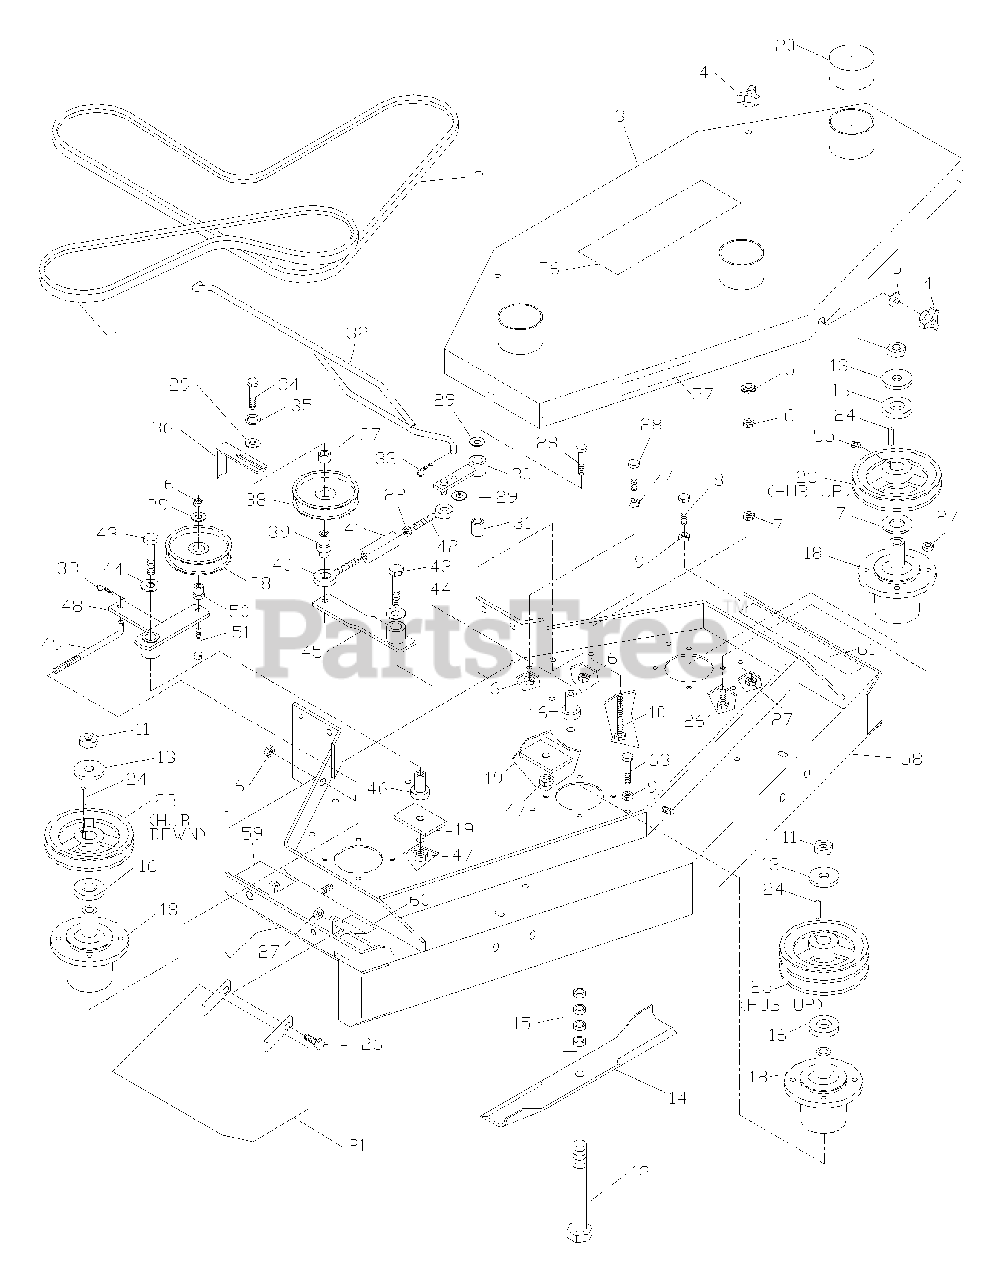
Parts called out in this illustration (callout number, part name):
1	AUX. BLADE BELT
2	BLADE BELT 48
3	48" BELT SHIELD
4	THREE PRONG KNOB
5	3/8 SEALING WASHER
8	HCS 5/16CX3
9	HFLN 5/16C
10	TAPBOLT-3/8C X 4 1/2
12	HCS 5/8F X 8 1/2
12	HCS 5/8F X 9(CENTER)
13	SUPPORT WASHER
14	BLADE 16 1/4"
15	BLADE SPACERS
17	MACH. BUSHING
18	HOUSINGASM.
21	DEFLECTOR CHUTE
22	5/16C HEX NUT
23	PULLEY W/SETSCRS
24	1/4SQ. KEY X 1 1/8
25	DOUBLE PULLEY
26	HCS 5/16C X 1
28	HCS 3/8C X 2 1/4
29	FW 3/8 STD
30	ENGAGEMENT ARM
31	SLEEVE BUSHING
32	BLADE ROD 48"
33	#2 HAIRPIN
34	HCS 3/8C X 2 1/2
35	3/8 LOCK WASHER
38	IDLER PULLEY
39	EYEBOLT PIVOT
40	LEFT HAND EYEBOLT
41	TURNBUCKLE
42	RH. EYEBOLT
43	HCS 1/2C X 2 3/4
44	1/2 FLAT WASHER
46	IDLER SPINDLE
47	1/2C NYLOC NUT
48	AUX. IDLER ARM
49	TENSION ROD
50	IDLER FLANGE BUSHING
51	HCS 3/8C X 1 3/4
52	HCS 7/16C X 1 1/2
53	7/16 LOCK WASHER
54	7/16C HEX NUT
55	5/16 NYLOC SETSCREW
56	DECAL, HUSQVARNA
57	DECAL, NASCAR
58	48" DECK W/DECALS
59	DECAL, SEVERING
60	DECAL, CPSC
63	HCS 5/16C X 4
64	DECAL, ETS
